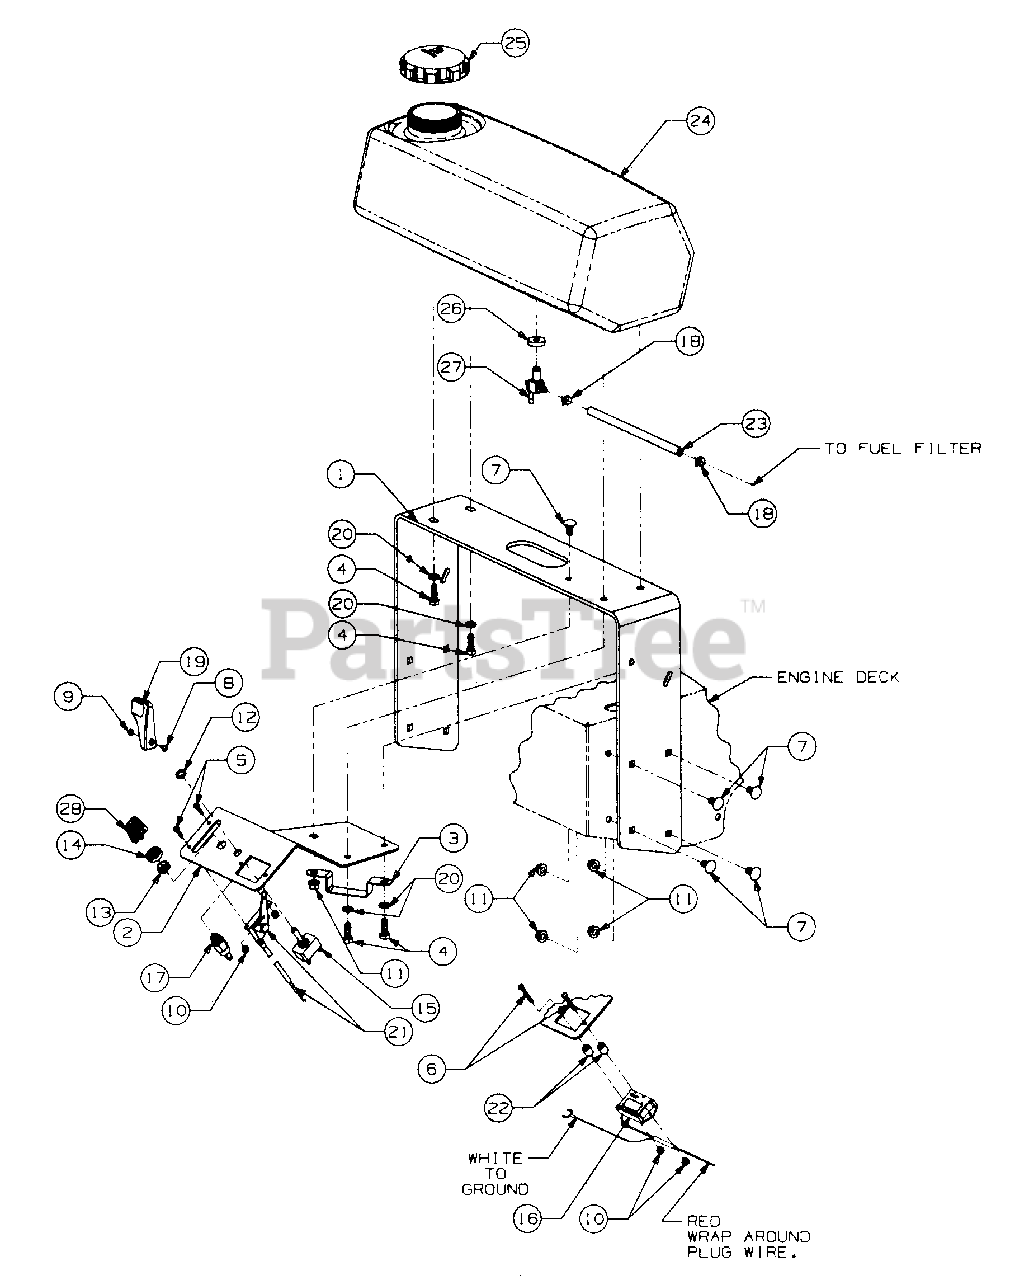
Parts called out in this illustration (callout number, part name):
1	Support, Lower Handle
2	Panel w/Graphic, Control
3	Bracket, Cable Retainer
4	Screw, Hex Cap, 3/8-16 X 1.0 Lg GR5
5	Screw Pan Hd Cutting, #10-25 X .75 Lg
6	Bolt, Pan Head, #10-24 X 1.50 Lg.
7	Bolt, Sht Nk Carriage, 3/8-16 X .75 Lg GR5
8	Screw, Cross Rec Truss Hd, #8-32 X .38 Lg
9	Nut, Hex, #8-32
10	Nut, Hex Nylock, #10-24
11	Nut, Hex Flanged Lock, 3/8-16
12	Nut, Hex, 1/2-27 X .100 Thk
13	Nut, Ignition Switch, 5/8-32
14	Cap, Ignition Switch
15	Switch, PTO
16	Meter, Hour/Tach, Model TT226NR-2C
17	Switch, Ignition
18	Clamp, Hose
19	Knob, Throttle Control
20	Washer, Lock, 3/8
21	Control, Throttle
22	Spacer, .315 ID X .50 OD X .52 Lg.
23	Line, Fuel - 9" Lg - Order bulk fuel line part no. 759-3330, 10 ft Lg
24	Tank, Fuel
25	Cap, Fuel
26	Grommet, Shutoff Valve
27	Valve, Fuel Shutoff
28	Key, Ignition (Set of 2)
